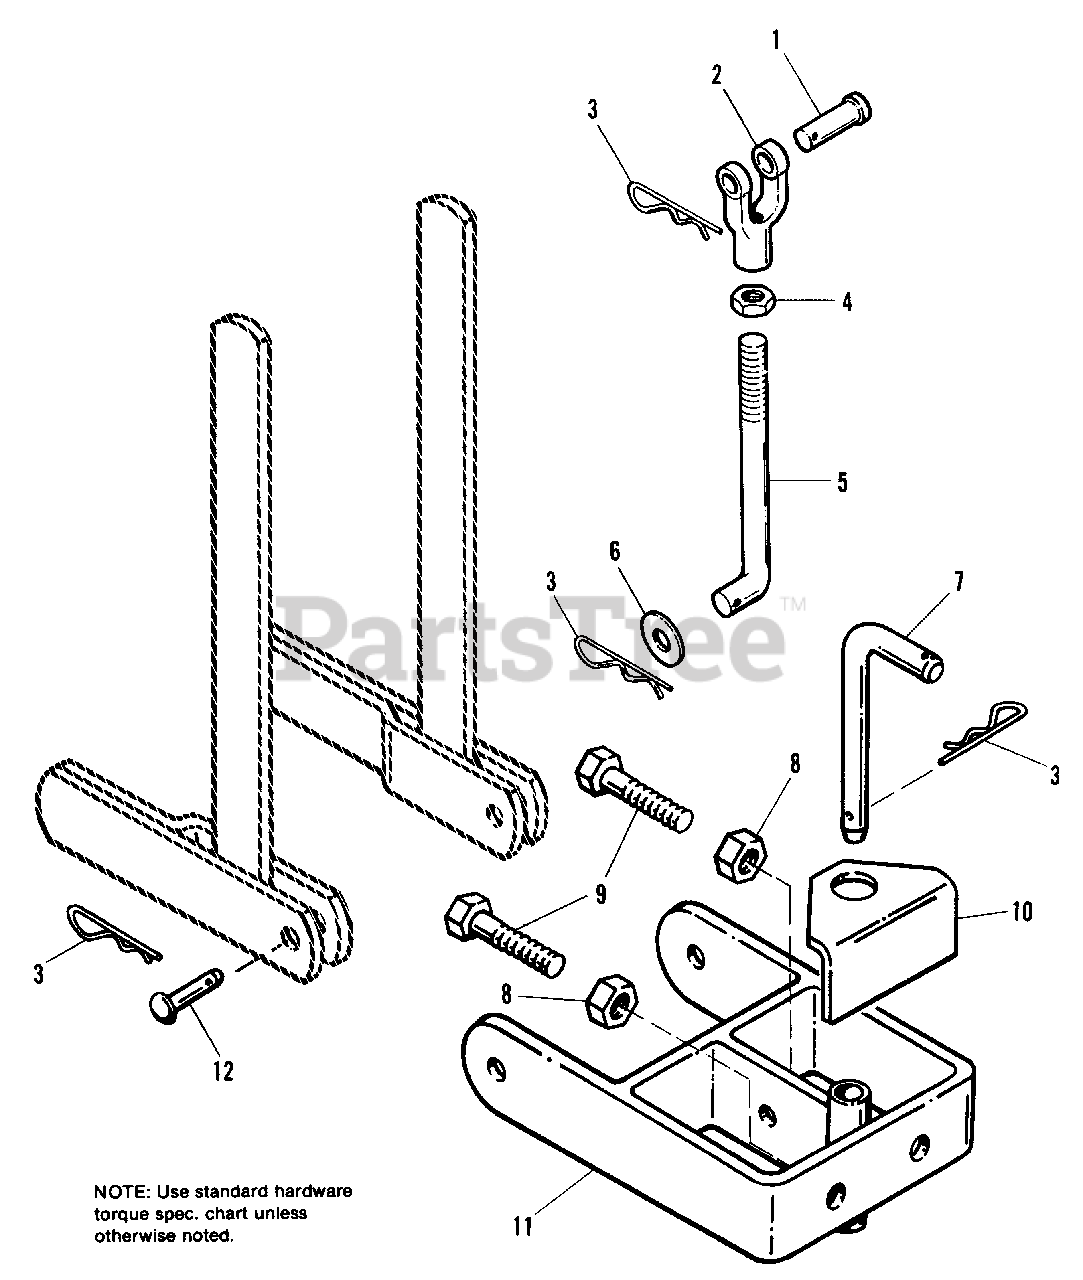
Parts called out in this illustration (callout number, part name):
1	PIN, YOKE
2	YOKE, End Adj.
3	CLIP, Spring
4	LOCKNUT, Hex, Jam, 1/2-20
6	WASHER, Plain, 1/2
8	NUT, Hex, Full, 5/8-11
9	CAPSCREW, Hex Hd., 5/8-11 x 2-1/4
10	PLATE, Stabilizer
11	CLEVIS ASSY.
